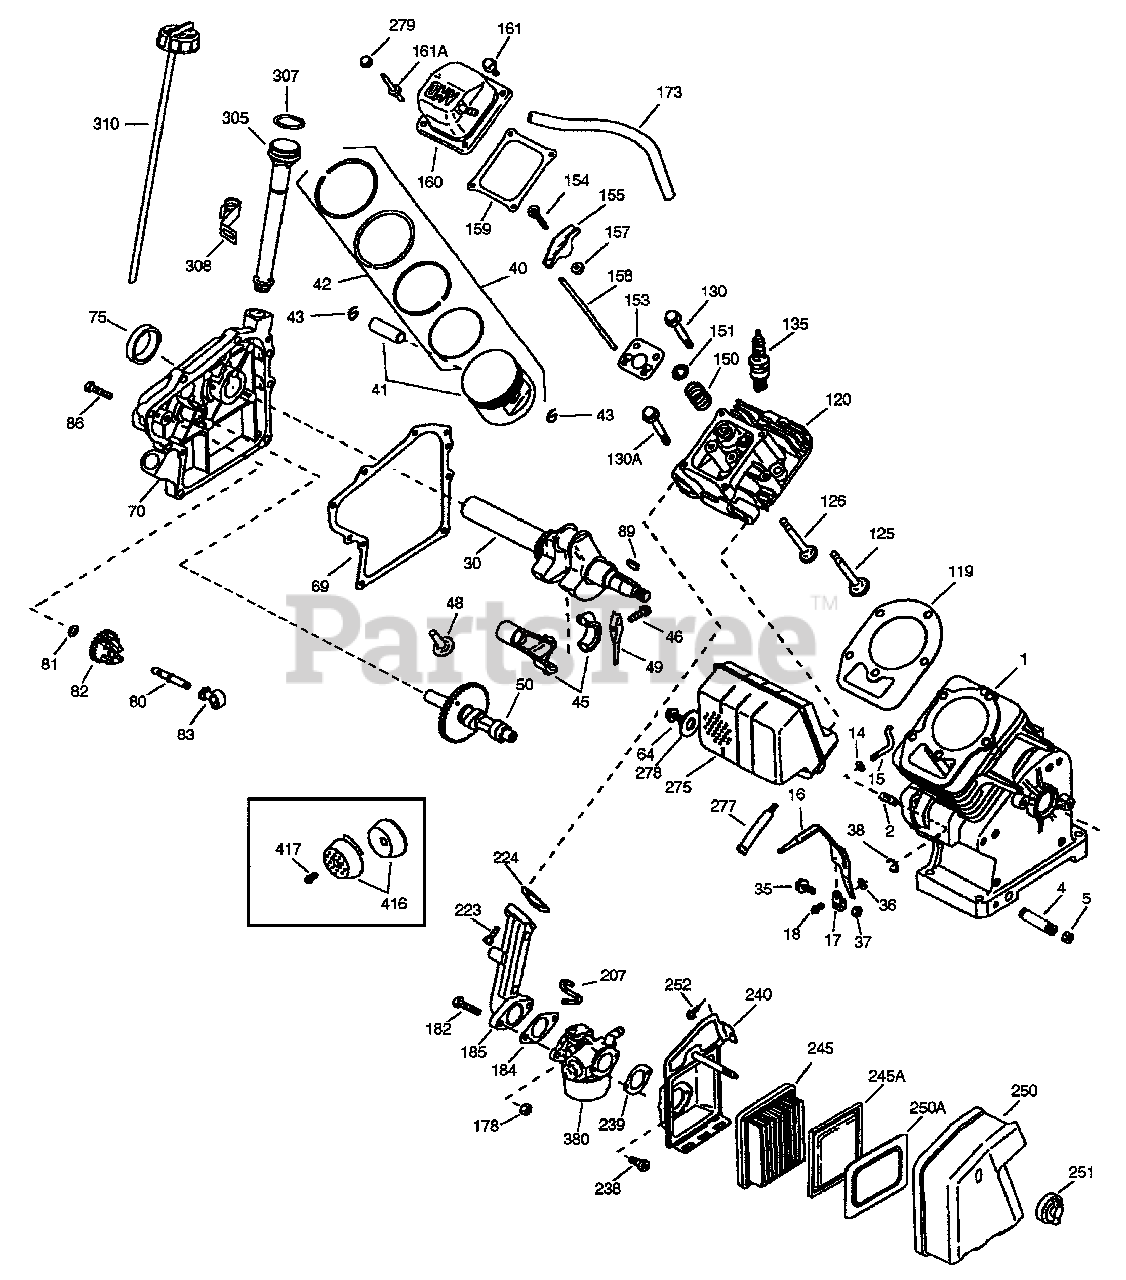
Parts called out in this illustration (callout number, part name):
2	Dowel Pin
4	Oil Drain Extension
5	Extension Cap
15	Governor Rod
16	Governor Lever
17	Governor Lever Clamp
18	Screw, Torx T-15, 8-32 x 3/8"
30	Crankshaft
35	Screw, 10-32 x 3/4"
36	Lock Washer
37	Lock Nut, 10-32
38	Retaining Ring
40	Piston, Pin, Ring Set (Std)
41	Piston & Pin Assy (Std)
42	Ring Set (Std)
43	Piston Pin Retaining Ring
45	Connecting Rod Assy
46	Connecting Rod Bolt
48	Valve Lifter
49	Oil Dipper
64	Screw, 1/4-20 x 1-1/8"
69	Cylinder Cover Gasket
70	Cylinder Cover
80	Governor Shaft
82	Governor Gear Assy
83	Governor Spool
86	Screw, 1/4-20 x 1-1/4"
89	Flywheel Key
119	Cylinder Head Gasket
120	Cylinder Head
125	Exhaust Valve (Std)
126	Intake Valve (Std)
130	Screw, 5/16-18 x 1-1/2"
130A	Screw, 5/16-18 x 2-41/64"
135	Resistor Spark Plug (RN4C)
150	Valve Spring
151	Valve Spring Cap
153	Push Rod Guide
154	Rocker Arm Stud
155	Rocker Arm
157	Nut, 1/4-28"
159	Rocker Arm Cover Gasket
160	Rocker Arm Cover
161	Screw, 1/4-20 x 31/64"
173	Breather Tube
178	Nut, 1/4-20"
182	Screw, 1/4-20 x 1"
184	Carburetor to Intake Pipe Gasket
185	Intake Pipe
207	Throttle Link
223	Screw, 1/4-20 x 1"
224	Intake Pipe Gasket
238	Screw, 10-32 x 1/2"
239	Air Cleaner Gasket
240	Air Cleaner Body
245	Air Cleaner Filter
245A	Air Cleaner Filter (Poly)
250	Air Cleaner Cover
250A	Air Cleaner Baffle
252	Screw, 10-32 x 1/2"
275	Muffler
277	Screw, 1/4-20 x 2-9/32"
279	Nut & Lock Washer
305	Oil Fill Tube
308	Fill Tube Clip
380	Carburetor
416	Spark Arrestor Kit
417	Screw, 8-32 x 3/8"
